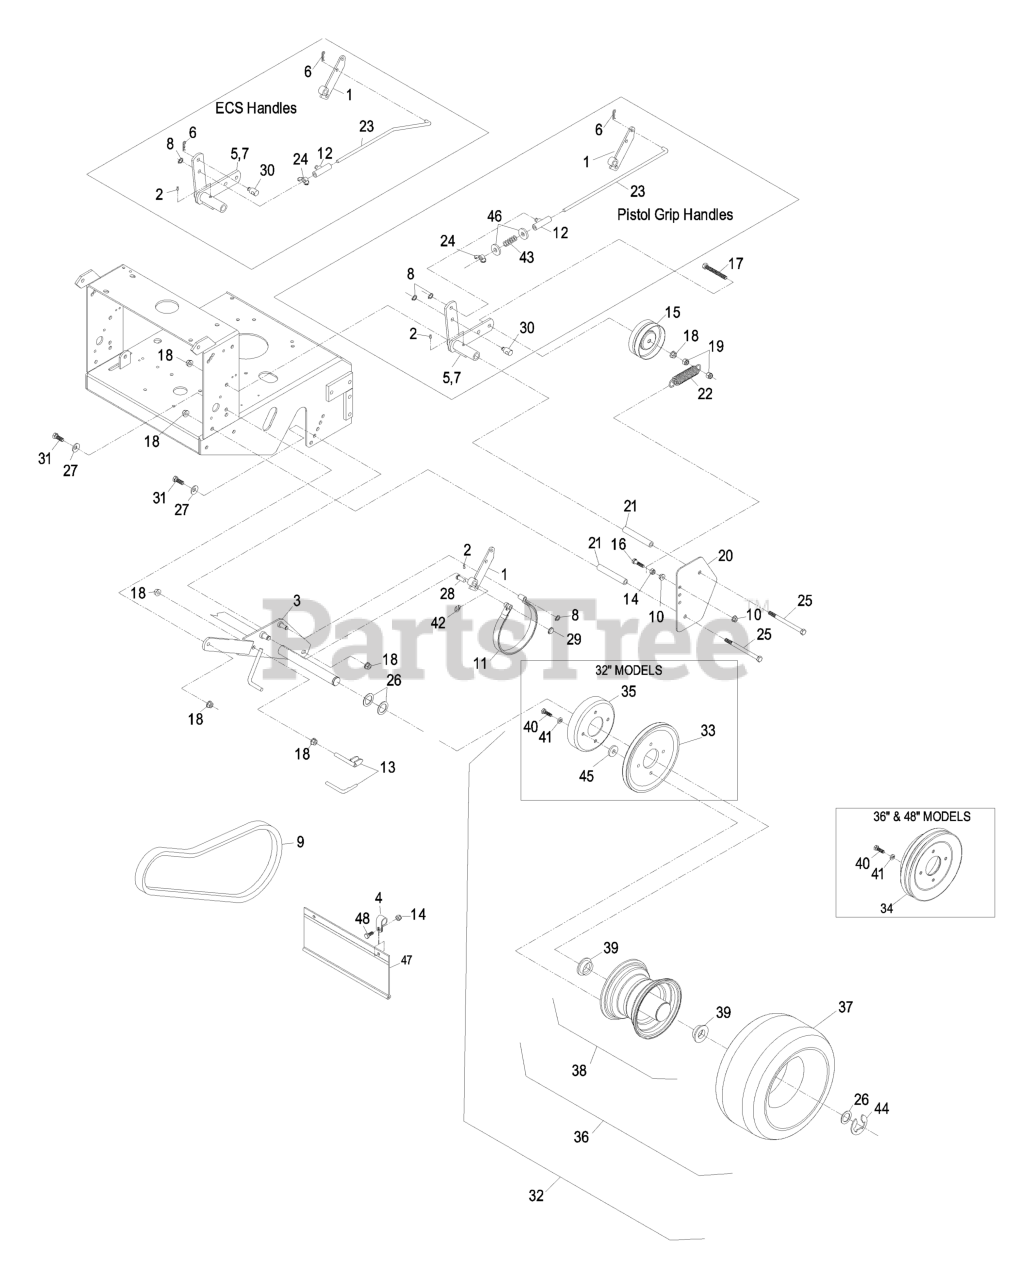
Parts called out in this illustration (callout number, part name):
1	ARM-BRAKE
2	FITTING-GREASE
4	CLAMP-R
6	PIN-COTTER
8	RING-RETAINING
9	BELT,WHEEL DRIVE
11	BAND-BRAKE
12	SWIVEL-BRAKE
13	SCRAPER
14	NUT-LOCK, NI
15	IDLER-WHEEL, DRIVE
16	SCREW-HH
17	SCREW-HH
18	NUT-HHF, WHIZ
19	NUT-LOCK, NI
20	SHIELD-WHEEL, DRIVE
21	SPACER-SHIELD
22	SPRING-EXTENSION
23	LINKAGE-BRAKE
24	WINGNUT-NYLOCK
25	SCREW-HH
26	WASHER-SPACER
27	WASHER-BELLEVILLE
28	PIN-CLEVIS
29	RING-RETAIN,PUSH,EXT,FLAT
30	SWIVEL-LEVER, DRIVE
31	SCREW-HH
32	DRIVE WHEEL ASM
33	SHEAVE-WHEEL, DRIVE
34	DRUM AND SHEAVE ASM
35	DRUM-BRAKE
36	WHEEL AND TIRE ASM
37	TIRE-TURFMASTER
38	WHEEL AND HUB ASM
39	BEARING-FLANGED
40	SCREW-HH
41	WASHER-LOCK
42	RING-RETAINING, EXTERNAL
43	SPRING-COMPRESSION
44	RING-SNAP
46	WASHER-PLAIN
47	SHIELD-TRAILING
48	SCREW-HH
